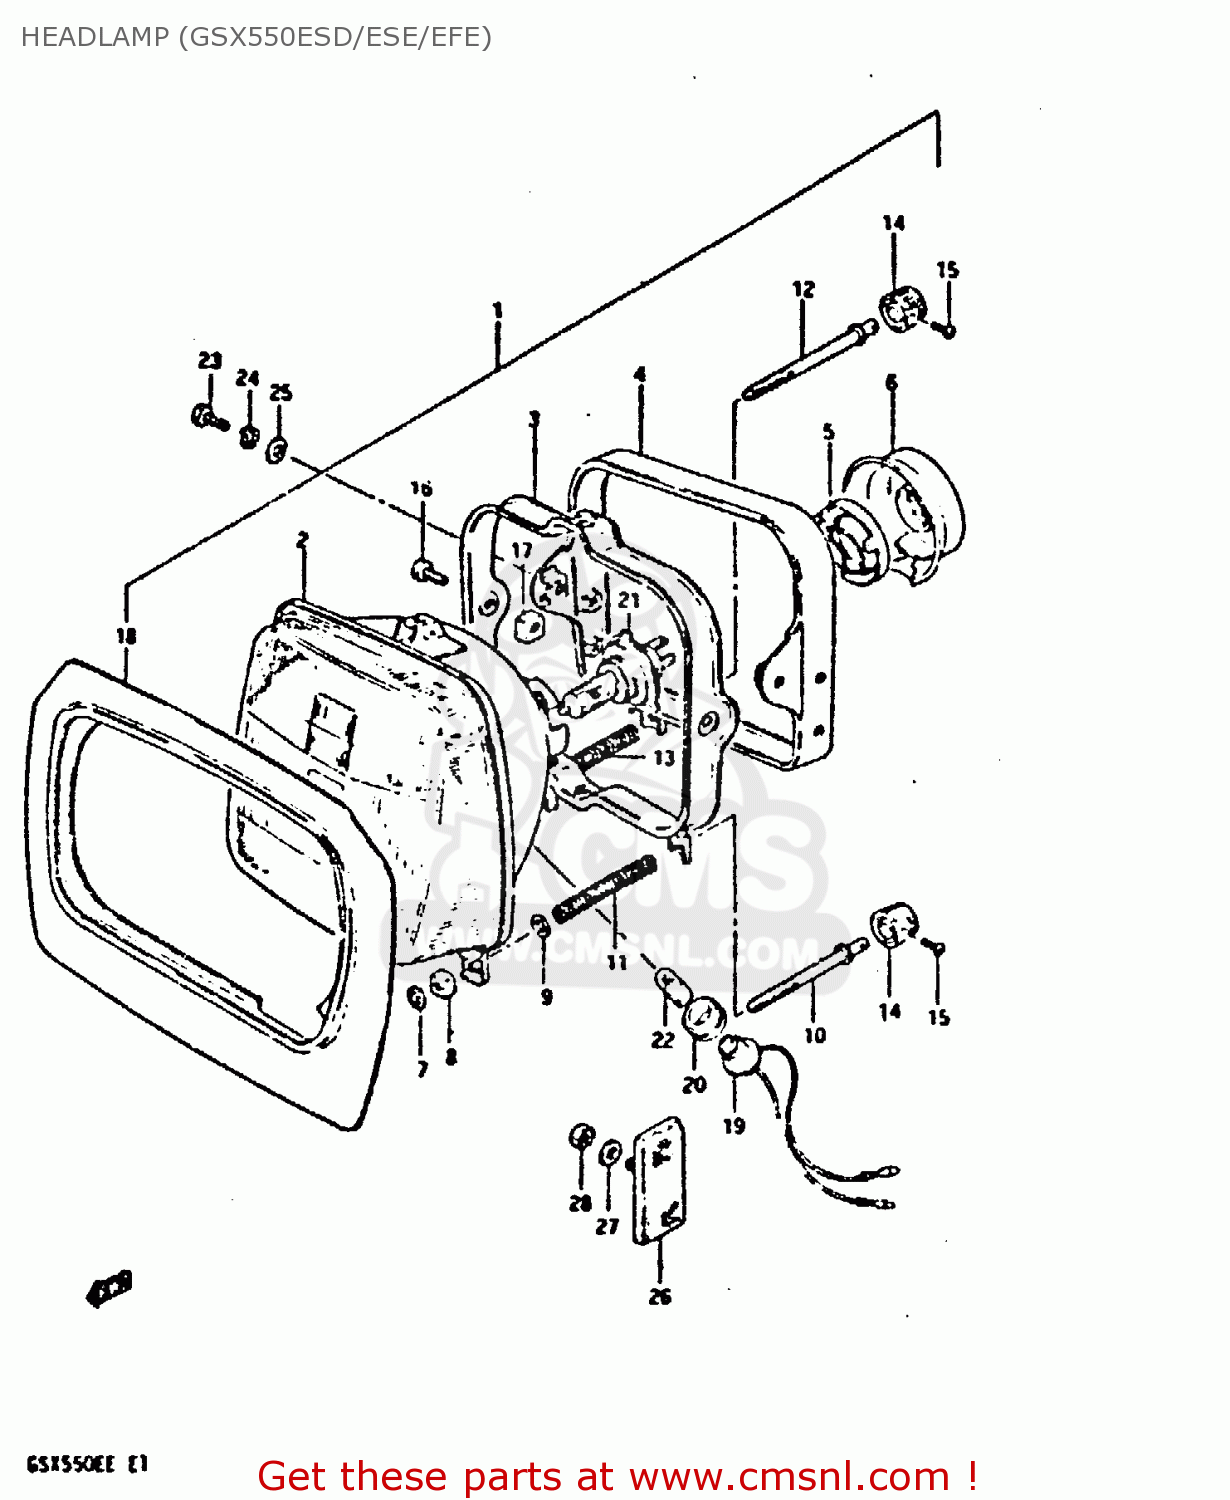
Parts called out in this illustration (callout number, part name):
1	HEADLAMP ASSY
2	UNIT
3	RING,MOUNTING
4	HOUSING,LAMP UNIT
5	HOLDER
6	COVER,HEADLAMP SOCKET
7	NUT,HEADLAMP ADJUSTER
8	NUT,HEADLAMP ADJUSTER
9	WASHER
10	SCREW,HEADLAMP ADJUST
11	SPRING
12	SCREW,ADJUSTING
13	SPRING
14	KNOB,ADJUSTER
15	SCREW
16	SCREW
17	NUT
18	SHADE
19	SOCKET
20	JOINT,RUBBER
21	BULB(12V60/55W,H4)
22	BULB(12V4W)
23	BOLT
24	WASHER,LOCK
25	WASHER, LOWER
